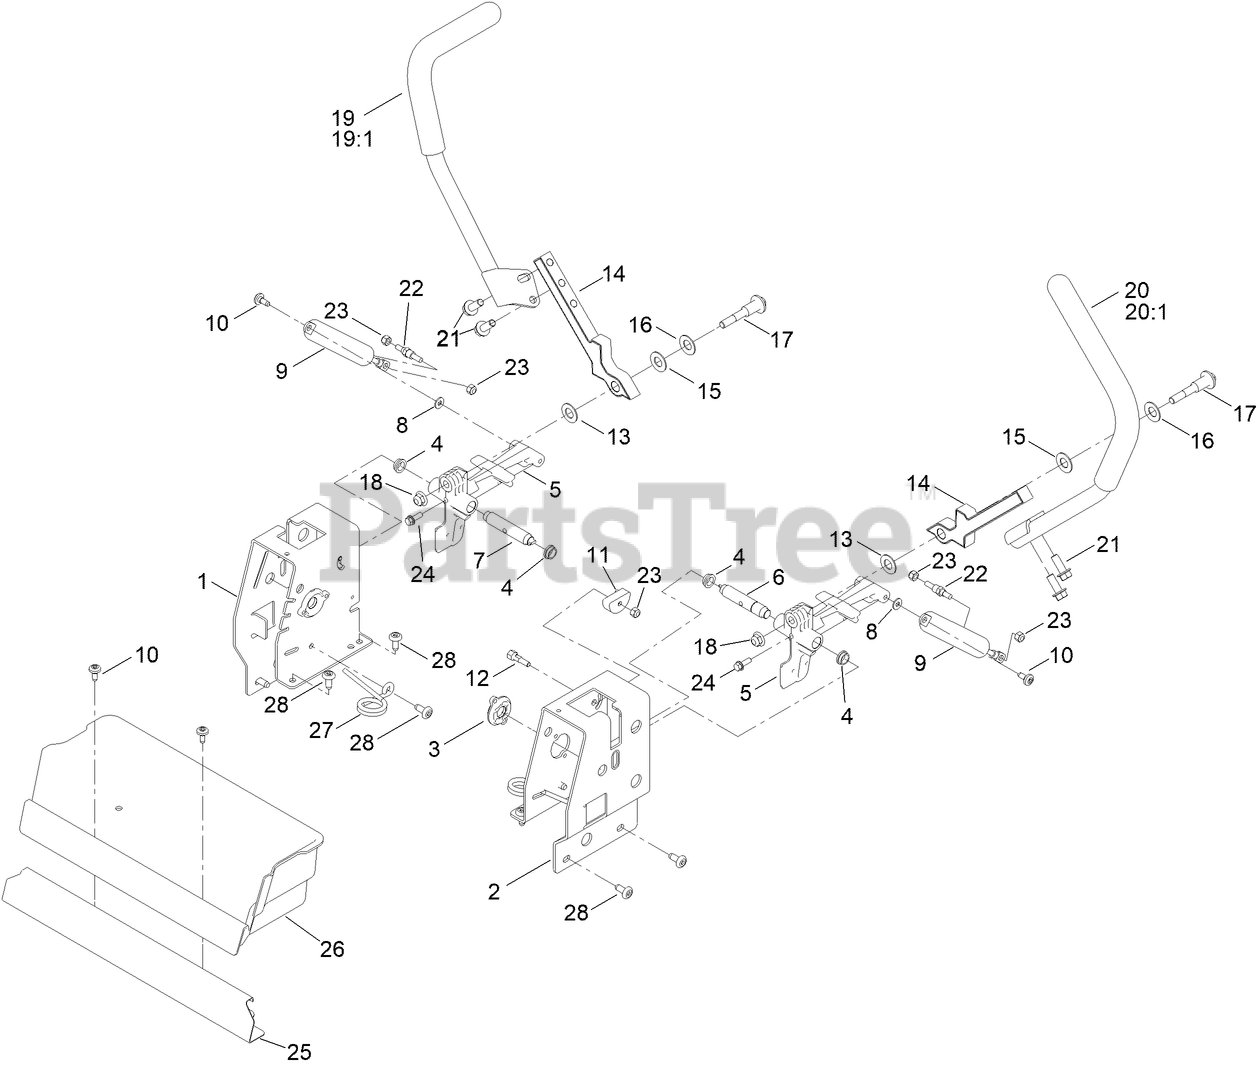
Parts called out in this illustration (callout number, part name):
1	PLATE-CONTROL BOX, RH
2	PLATE-CONTROL BOX, LH
3	SPACER-SENSOR
4	BUSHING-FLANGE
5	ARM-ACTUATOR
6	PIN-LEVER PIVOT, LH
7	PIN-LEVER PIVOT, RH
8	WASHER
9	DAMPER-NON CAVITATING
10	SCREW-SHOULDER
11	ECCENTRIC
12	BOLT-PIVOT, ECCENTRIC
13	WASHER-NYLON
14	ARM-CONTROL
15	WASHER
16	WASHER-BELLEVILLE
17	BOLT-PIVOT
18	NUT-HF, NI
19	HANDLE-CONTROL, RH
20	HANDLE-CONTROL, LH
21	SCREW-HHF
22	STUD-DAMPER
23	NUT-HEX
24	SCREW-HHF
25	PLATE-KICK
26	BOX-STORAGE
27	SPRING-TORSION
